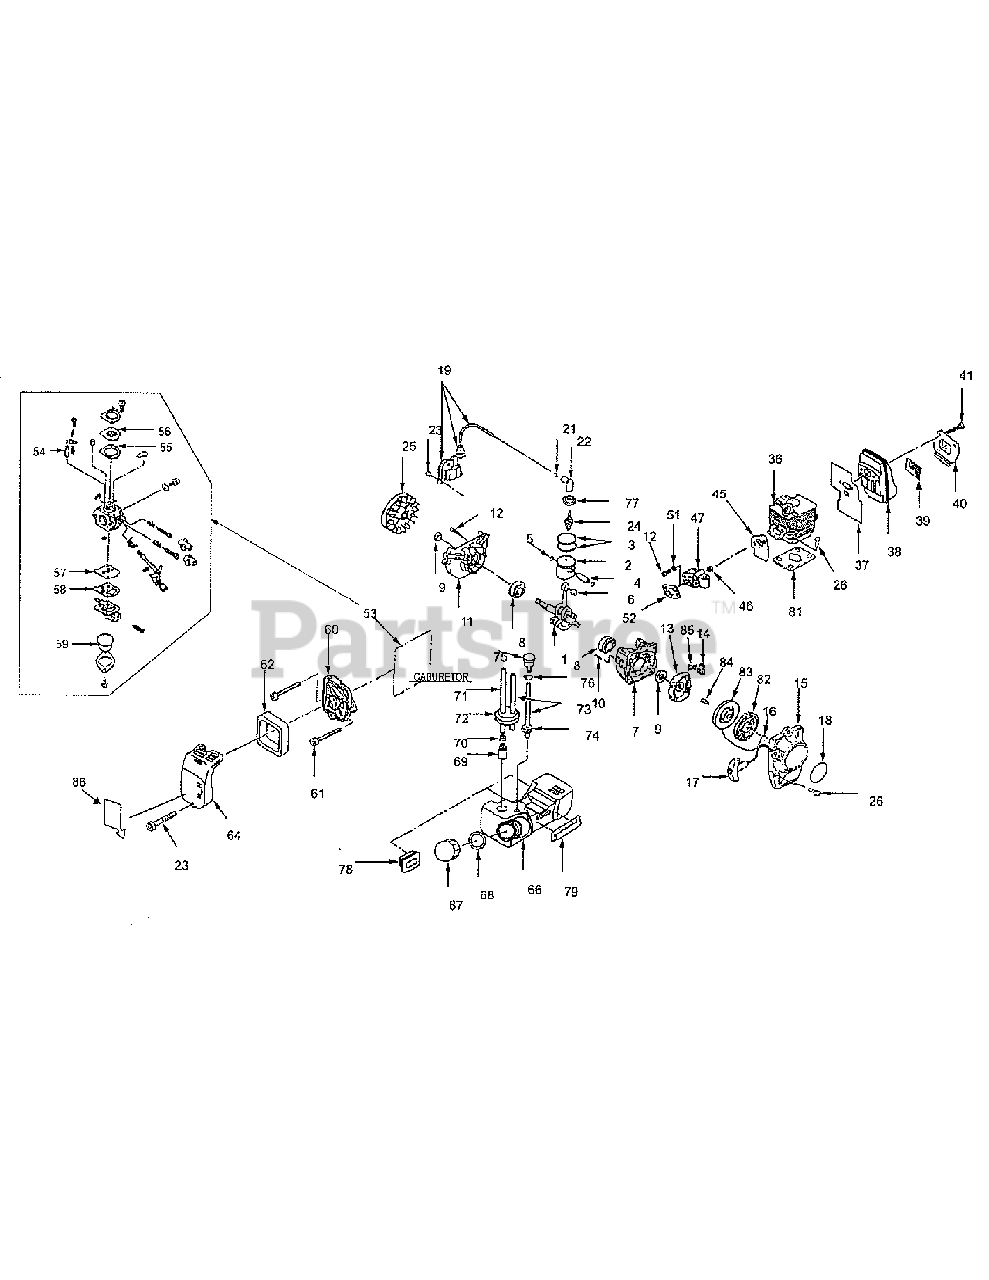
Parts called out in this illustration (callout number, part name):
2	Piston Assembly (Includes 2 Ref. 3)
3	Ring, Piston
4	Pin Piston
5	Clip, Piston Pin
6	Bearing, Needle
7	Crankcase Assembly (Includes 1ea Ref. 8, 9 and 2 ea. Ref. 10)
8	Bearing, Ball
11	Crankcase Assembly (Includes 1 ea. Ref. 8 and 9
13	Pulley Assembly Starter (Includes 1 ea. Ref. 14 and 85)
15	Recoil Assembly (Includes 1 ea. Ref. 16, 17, 82, 83 and 84)
16	Rope, Starter
17	Knob Starter
18	Name Plate
19	Coil Assembly Ignition
22	Cap, Plug
24	Spark Plug
25	Flywheel, Magneto
36	Cylinder
40	Baffle Plate, Outer
41	Bolt, M5x48
47	Insulator
53	Carburetor Assembly (Includes 1 ea Ref. 54, 55, 56, 57, 58 and 59)
54	Valve, Float
56	Diaphragm, Metering
57	Diaphragm, Pump
60	Case, Air Silencer
61	Bolt, M5x50
62	Element, Air Filter
67	Cap Assembly, Fuel Tank (Includes 1 ea Ref. 68)
69	Filter, Fuel
75	Valve, Reversing
80	Gasket Kit (Includes 1 ea. Ref. 37, 45 and 52)
81	Gasket, Cylinder
82	Spring, Spiral
85	Spring, Return
